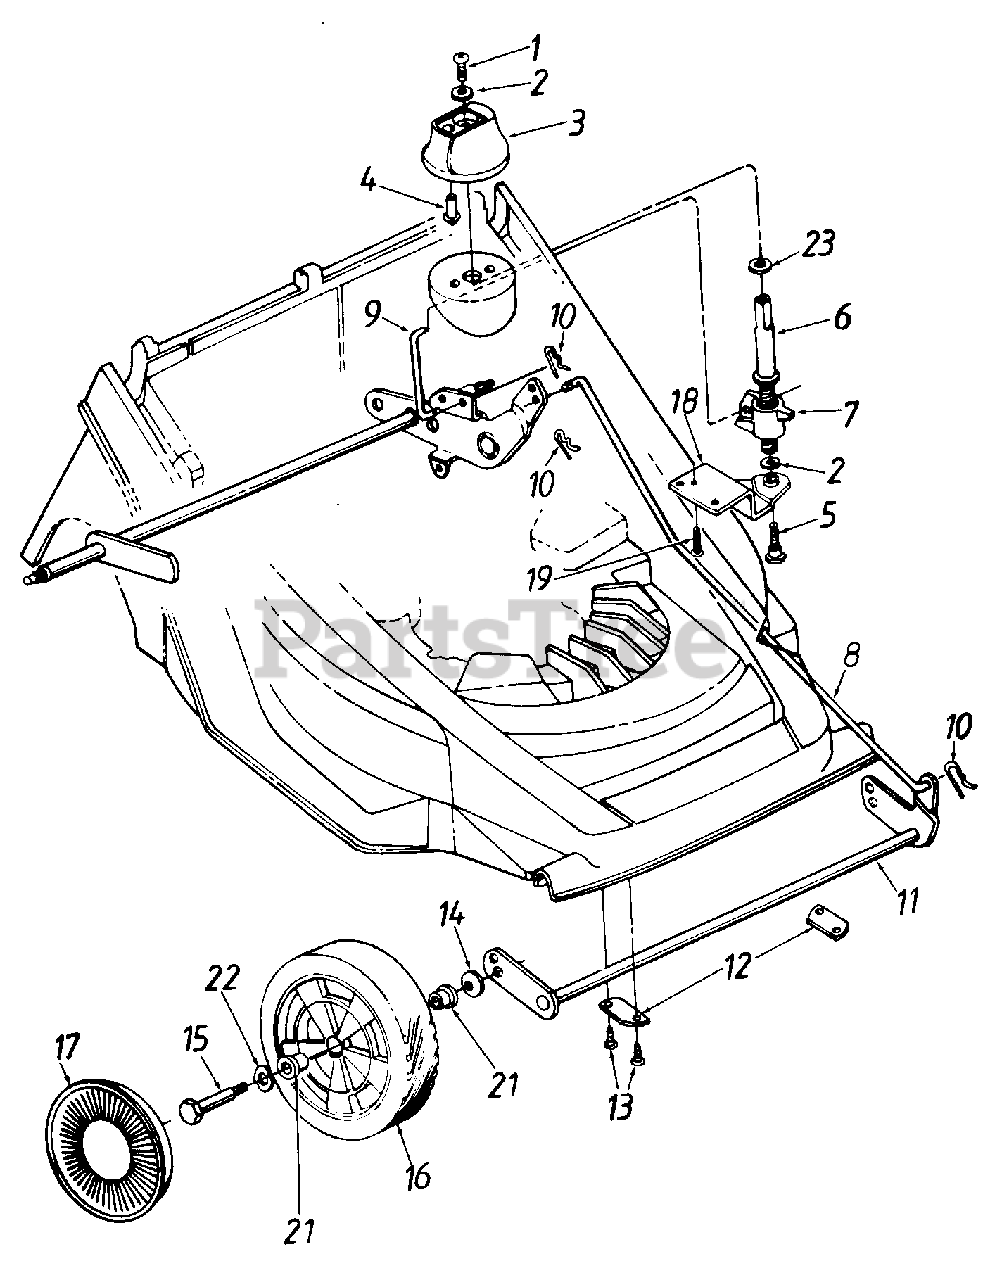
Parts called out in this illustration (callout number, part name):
1	Truss Mach. Scr. 1/4-20 x .75" Lg.
2	L-Wash. 1/4" I.D.
3	Plastic Knob
4	Ball Plunger
5	Shld. Bolt .342" Dia. x .268" Lg.
6	Height Adjuster Spindle
7	Spindle Guide
8	Height Adjustment Rod
9	Height Adjustment Link
10	Int. Cotter Pin 5/16" Dia.
11	Front Axle Ass'y.
12	Axle Mounting Plate
13	Truss Mach. Hi-Riser Tap Scr. #12x 1" Lg.
14	Bell-Wash. .38" I.D. x .88"
15	Shld. Bolt .498" Dia. x 1.45"
16	Front Wheel Ass'y. Comp.
17	Hub Cap
21	Ball Bearing
22	Wave Wash. .53" I.D.
23	Fl-Wash. .51" I.D. x 1" O.D.
